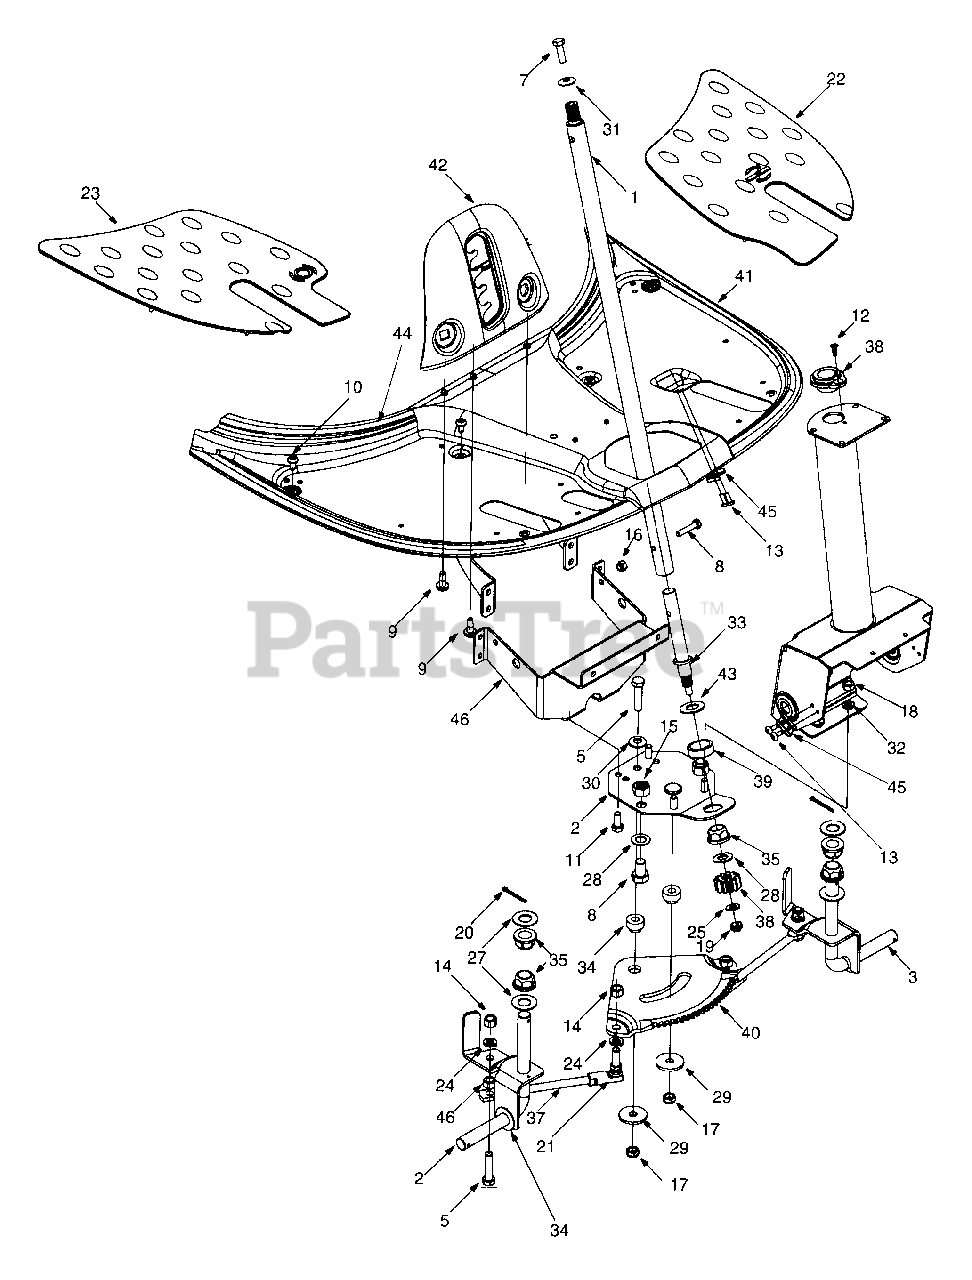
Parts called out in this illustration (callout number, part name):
3	Front Axle Assembly - L.H.
5	Hex Screw 3/8-24 x 1.5 Gr. 5
7	Hex Screw 5/16-18 x 1.00 Gr. 5
8	Hex Screw 1/2-13 x .75
9	TL Screw 5/16-18 x .75
10	AB Screw 1/4-14 x .625
11	Hex Screw 5/16-18 x .75 Grade 5
12	C-Sunk Phillips screw 10-16 x .62
13	Philips Screw 10-16 x .50
14	Hex Nut 3/8-24
15	Hex Nut 1/2-13
16	Top Lock Nut 1/4-20
17	Jam Nut 3/8-24
18	Hex nut 5/16-18
19	Hex Nut 5/16-24
20	Cotter Pin
21	Ball Joint
22	Floor Pad - L.H.
23	Floor Pad - R.H.
24	Lock Washer 3/8
25	Flat Washer.34 I.D. x 1.0 x .063
27	Flat Washer .64 I.D. x 1.24 x .06
28	Flat Washer .536 I.D. x .930 O.D. x .05
29	Flat Washer .38 I.D. x 1.38 O.D.
30	Bell Washer .401 x .870 x .063
31	Bell Washer .305 I.D. x .88 O.D. x .06
32	Lock Washer 5/16
33	Steering Adapter .625 dia. x 5.62
34	Spacer
35	Flange Bearing
37	Tie Rod
38	Steering Pinion Gear
39	Spacer
40	Steering Gear Segment
44	Switch Plate
45	Hex Nut 3/8-24
46	Grease
